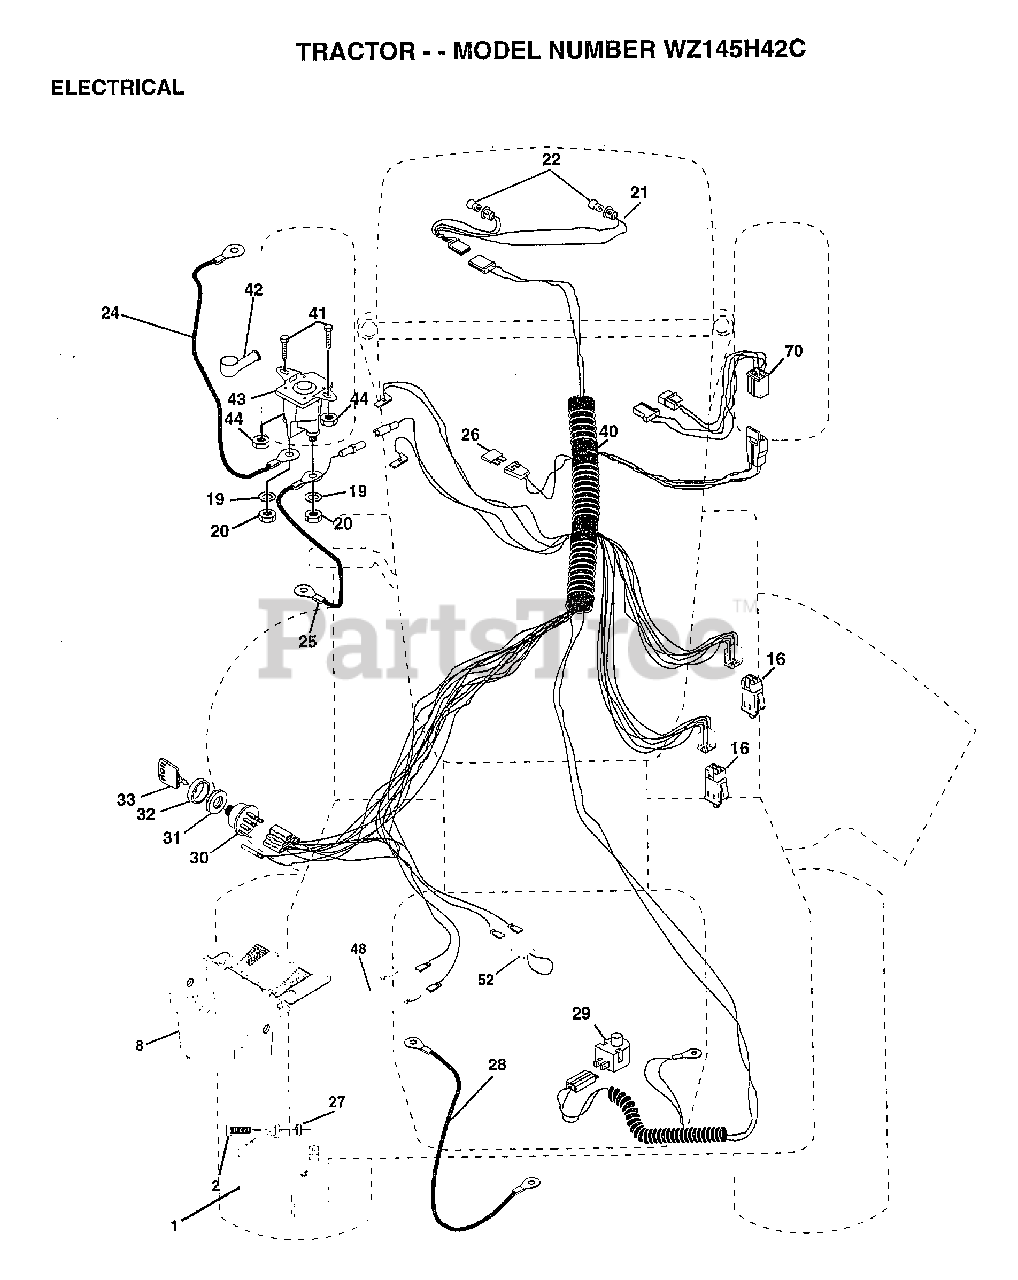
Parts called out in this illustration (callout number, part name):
2	BOLT LT
8	"CASE,BATTERY.MECH"
16	SWITCH INTERLOCK
20	NUT
21	HARNESS.ASM.LIGHT W/4152J
22	HEADLAMP BULB
24	"CABLE T, BATTERY"
25	CABLE.BTRY.6GA.RD
26	FUSE.15 AMP
27	NUT
28	CABLE T
29	SWITCH SEAT
30	SWITCH IGN 4POS
31	NUT IGNITION
32	COVER KEY SWITCH
33	KEY
40	HARNESS.IGNITION
41	BOLT HXHD FIN
44	NUT HXKEP 1/4X20
48	ADAPTER AMMETER
52	PROTECTION LOOP
70	HARNESS.ENGINE.B&S
